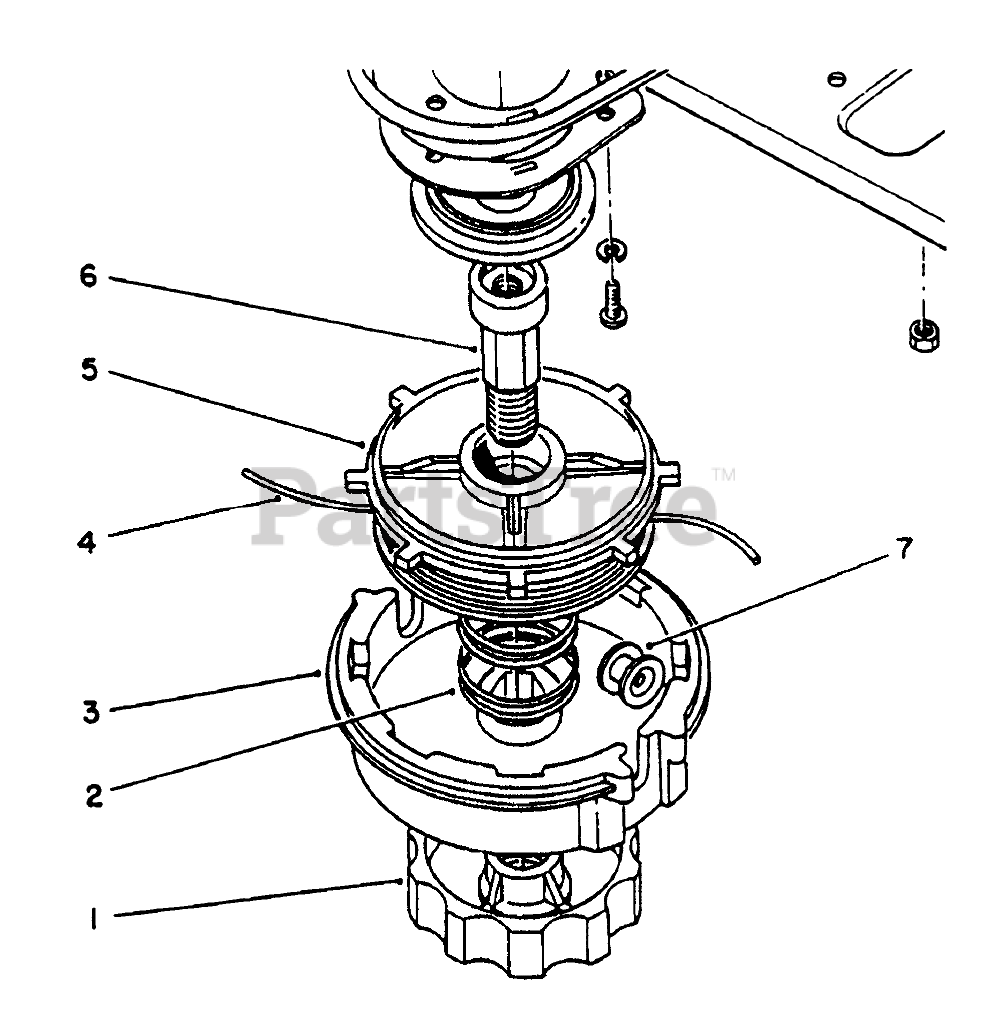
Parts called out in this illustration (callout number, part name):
1	LH KNOB(SERVICE ONLY)
2	SPRING (SERVICE)
3	SPOOL HSG (SERVICE ONLY
5	INNER SPOOL(SERV ONLY)
6	SHAFT (SERVICE ONLY)
7	EYELET(SERVICE)
